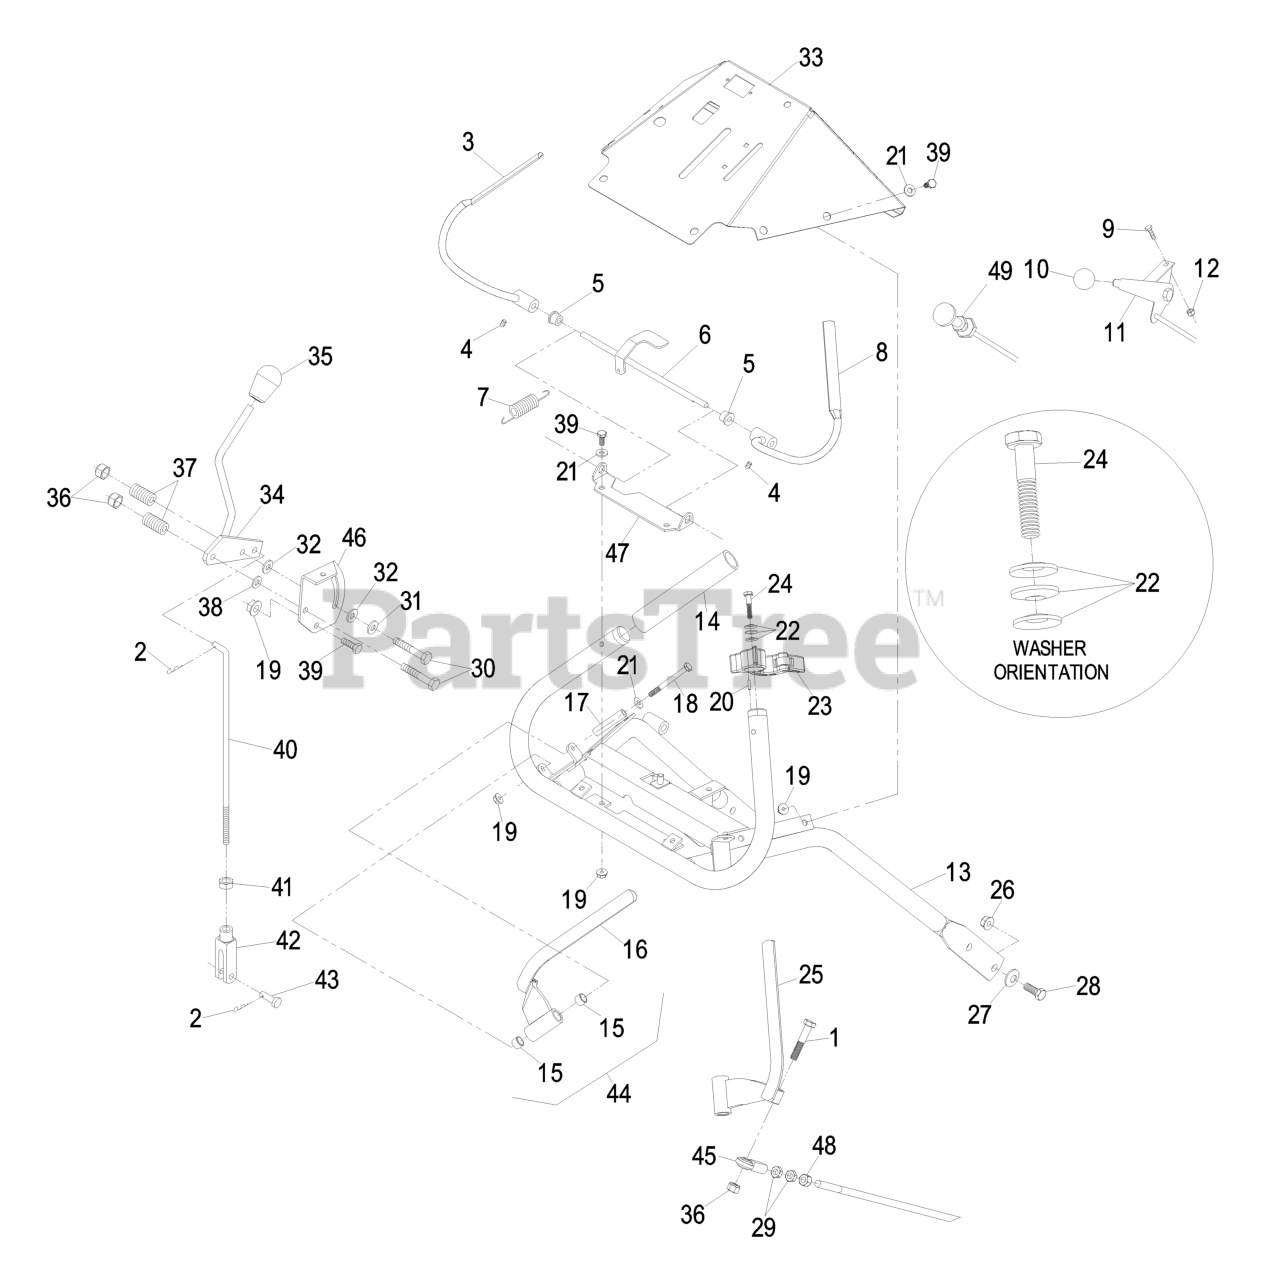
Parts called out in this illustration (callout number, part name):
1	SCREW-HH
2	PIN-COTTER
4	SCREW-SET
5	BUSHING-NYLON
6	WLD,OPC LEVER AXLE
7	SPRING-EXTENSION
9	BOLT-CARR
10	KNOB-BALL
11	THROTTLE CABLE ASM
12	NUT-LOCK, NI
13	WLD,TTH ECS HANDLE
14	GRIP-BAR, HANDLE
15	BUSHING-SLEEVE
16	DRIVE LEVER-ASM, LH
17	BUSHING-LEVER, DRIVE
18	SCREW-HH
21	WASHER-FLAT
22	WASHER-SPRING
23	ASM,LATCH RH THUMB
24	SCREW-HH
25	DRIVE LEVER-ASM, RH
26	NUT-HHF, WHIZ
27	WASHER-BELLEVILLE
28	SCREW-HH
29	NUT-HJ
30	SCREW-HH
31	WASHER-FRICTION
32	WASHER-FRICTION
33	KIT,TT ECS CONSOLE
35	KNOB, FE.LCKG. BLACK
36	NUT-LOCK, NI
37	SPRING-COMPRESSION
38	WASHER-PLAIN
39	SCREW-HH
40	ROD,SPEED CONTROL
41	NUT-JAM
42	YOKE-ADJUSTABLE
43	PIN-CLEVIS
44	DRIVE LEVER-ASM, RH
45	JOINT-BALL, END
46	BRACKET,SHIFTER SLIDE (PL
47	BRACKET,OPC AXLE
48	NUT-HEX
49	CONTROL-CHOKE
